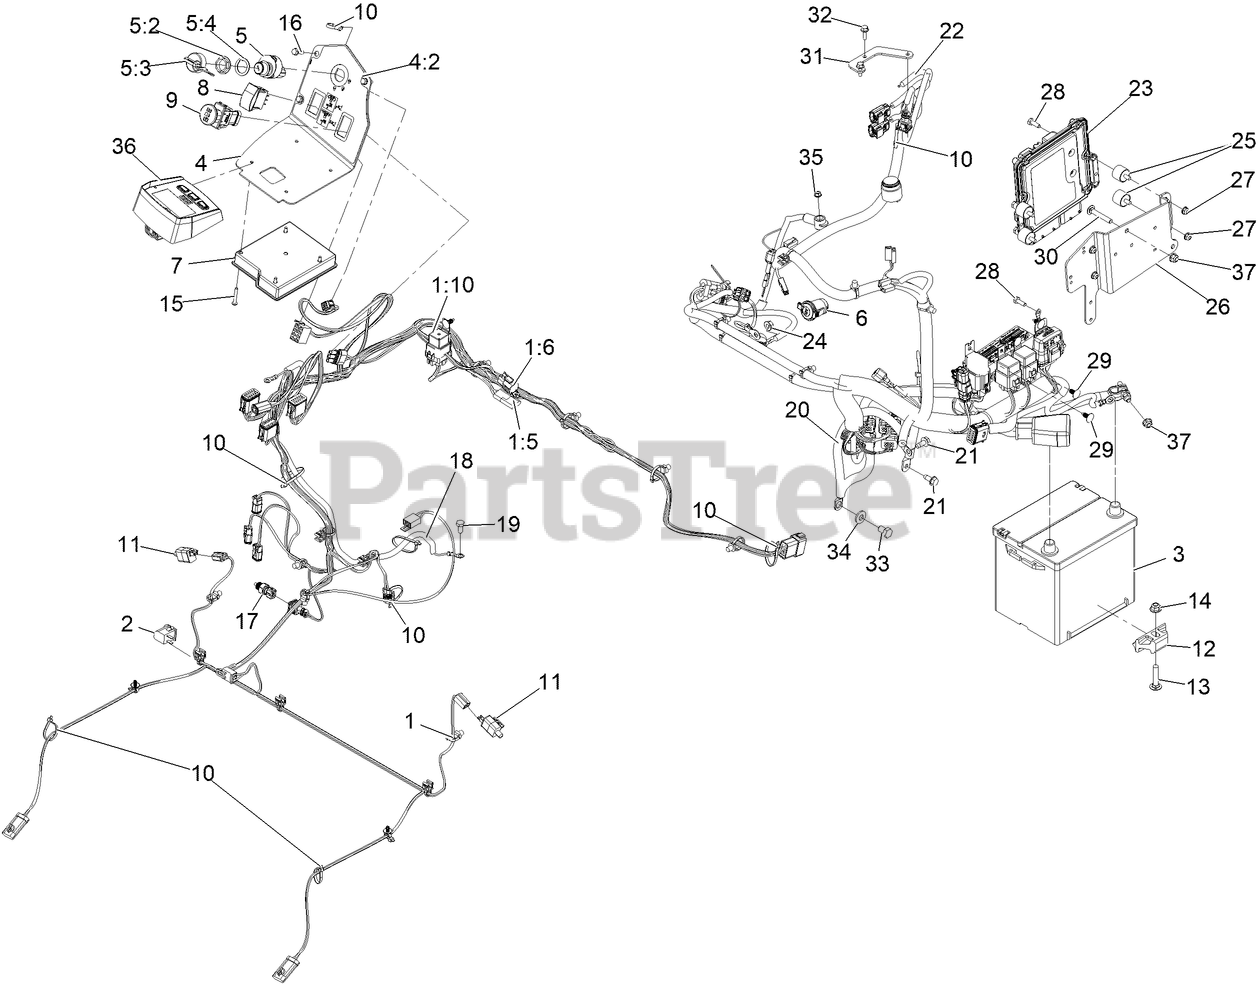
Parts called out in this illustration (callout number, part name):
1	HARNESS-WIRE, MAIN
1:5	Cap-Plug
1:6	CAP-PLUG, 6 WAY
1:10	RELAY-MINI
2	SWITCH-BAIL
3	Battery-Dry
4	CONSOLE ASM
4:2	DECAL-CONSOLE
5	IGNITION SWITCH ASM
5:2	NUT-MOUNTING
5:3	IGNITION KEY SET
5:4	WASHER-BACKUP
6	PORT-POWER, 12V
7	Module-Mcu
9	SWITCH-PTO, SEALED
10	TIE-CABLE
12	RETAINER-BATTERY
13	SCREW-CARR
14	NUT-HF, NI
15	SCREW-PPH
16	SCREW-HWH
17	SENSOR-TEMPERATURE
18	HARNESS-WIRE, JUMPER
19	SCREW-HH
20	CABLE-BATTERY
21	Screw-HWH 5/16-18 X 3/4 Tf
22	Harness-Wire, Yanmar
23	Electronic Control Unit
25	MOUNT-CYLINDRICAL
26	MOUNT-CONTROL UNIT, ENGIN
28	SCREW-HH
29	PLUG-PLASTIC
30	BOLT-CARR
31	BRACKET-WIRING, ENGINE
32	SCREW-HHF
33	SCREW-HH
34	WASHER-BELLEVILLE
36	MODULE, LDU
37	NUT-HF, NI
